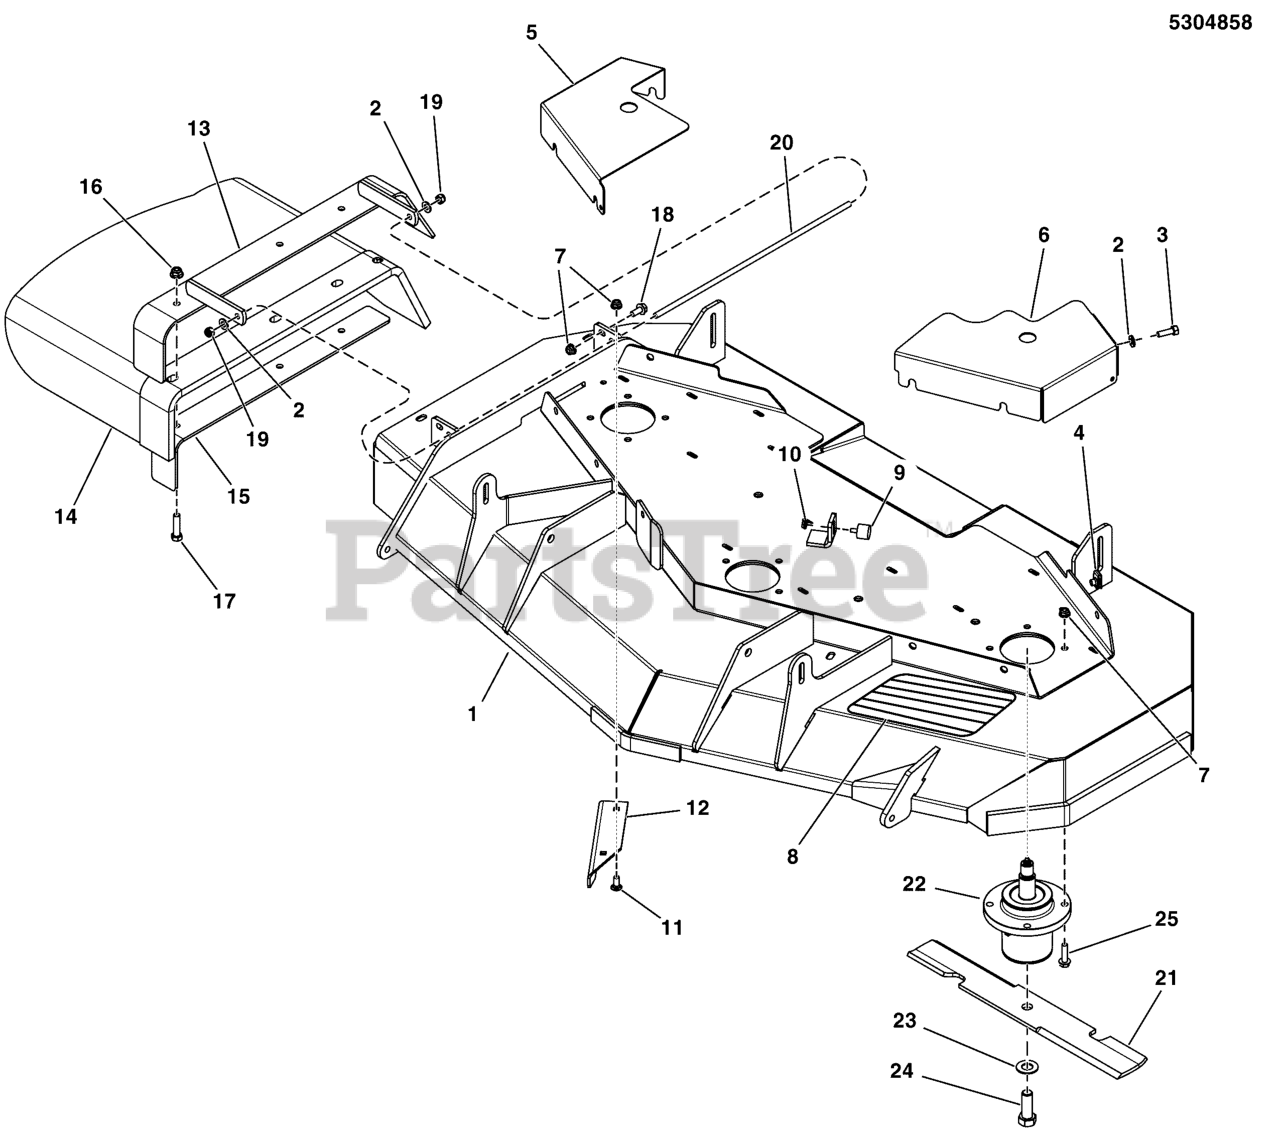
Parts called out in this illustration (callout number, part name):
1	DECK SHELL W/DECALS, 52, 125 (5422048D)
2	WASHER, 5/16" SAE
3	BOLT, 5/16-18 X 1 GD5 YZ
4	BODY CLIP, 5/16-18-7GA MATERIAL
5	GUARD, RH 52", 560/700/125
6	GUARD, 52 DECK, LH - RED
7	NUT, 5/16-18 HEX NYLOCK FLANGE
8	SAFETY WALK, 4.00 X 7.50
9	BUMPER, RUBBER 1/4-20
10	NUT, 1/4-20 HEX SERR. FLANGE
11	BOLT, 5/16-18 X 3/4, CARRIAGE
12	PLATE, DEFLECTOR, 52 DECK - BLK
13	WELD, MOUNT, DISCHARGE CHUTE - BLK
14	CHUTE, RUBBER DISCHARGE (5104442)
15	SUPPORT, DISCHARGE CHUTE - BLK
16	NUT, 3/8-16 HEX NYLOCK FLANGE
17	BOLT, 3/8-16 X 1-1/2, CARRIAGE, GD5, CZ
18	BOLT, 5/16-18 X 3/4 GD5
19	NUT, 5/16-24 HEX NYLON LOCK
20	ROD, MOUNT, CHUTE 61, CZ
21	BLADE, 18 X .25 X 2.5, 1 X 3.5 (SET OF 3)
22	ASSM, SPINDLE, LOW PROFILE
23	WASHER, 5/8 GRADE 8, YZ
24	BOLT, 5/8-11 X 1-3/4 GD8
25	BOLT, 5/16-18 X 1 1/4 FLANGE
